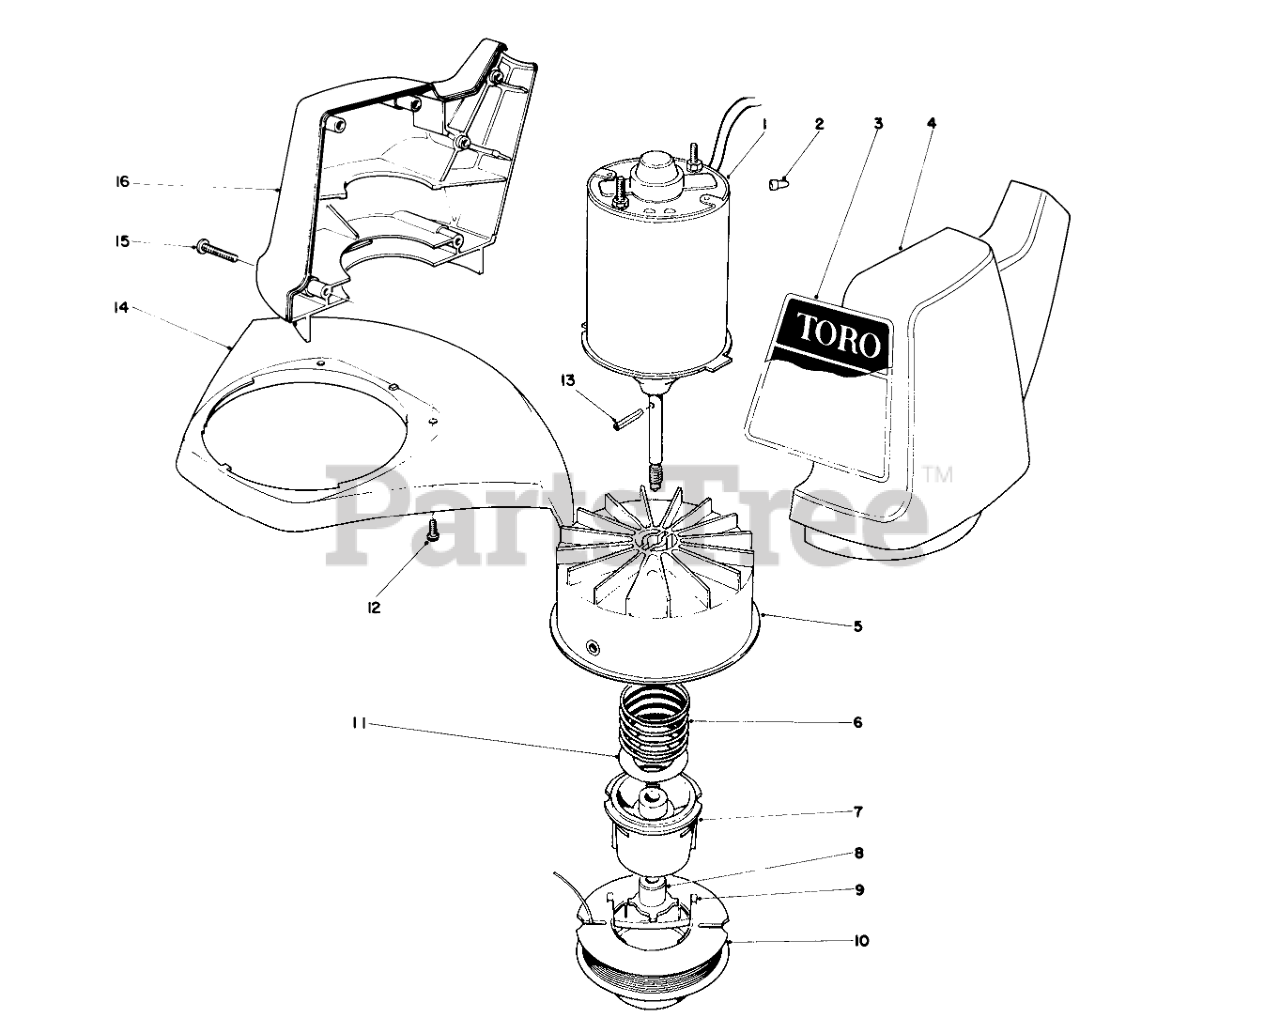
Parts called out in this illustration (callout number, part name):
1	MOTOR
2	CONNECTOR WIRE JOINT
3	DECAL
4	Housing-L.H.
5	DRUM W/EYELET
6	SPRING COMPRESSION
7	SPOOL CORE
8	DRIVER
9	SADDLE-SPOOL CAP
10	38 ft. .080 dia. Cutting Line Prewound on Spool
11	WASHER-FLAT
12	#8 X .625" PHILPS PAN H
13	COIL PIN
14	SHIELD ASM
15	SCREW-PPH
16	Housing-R.H.
